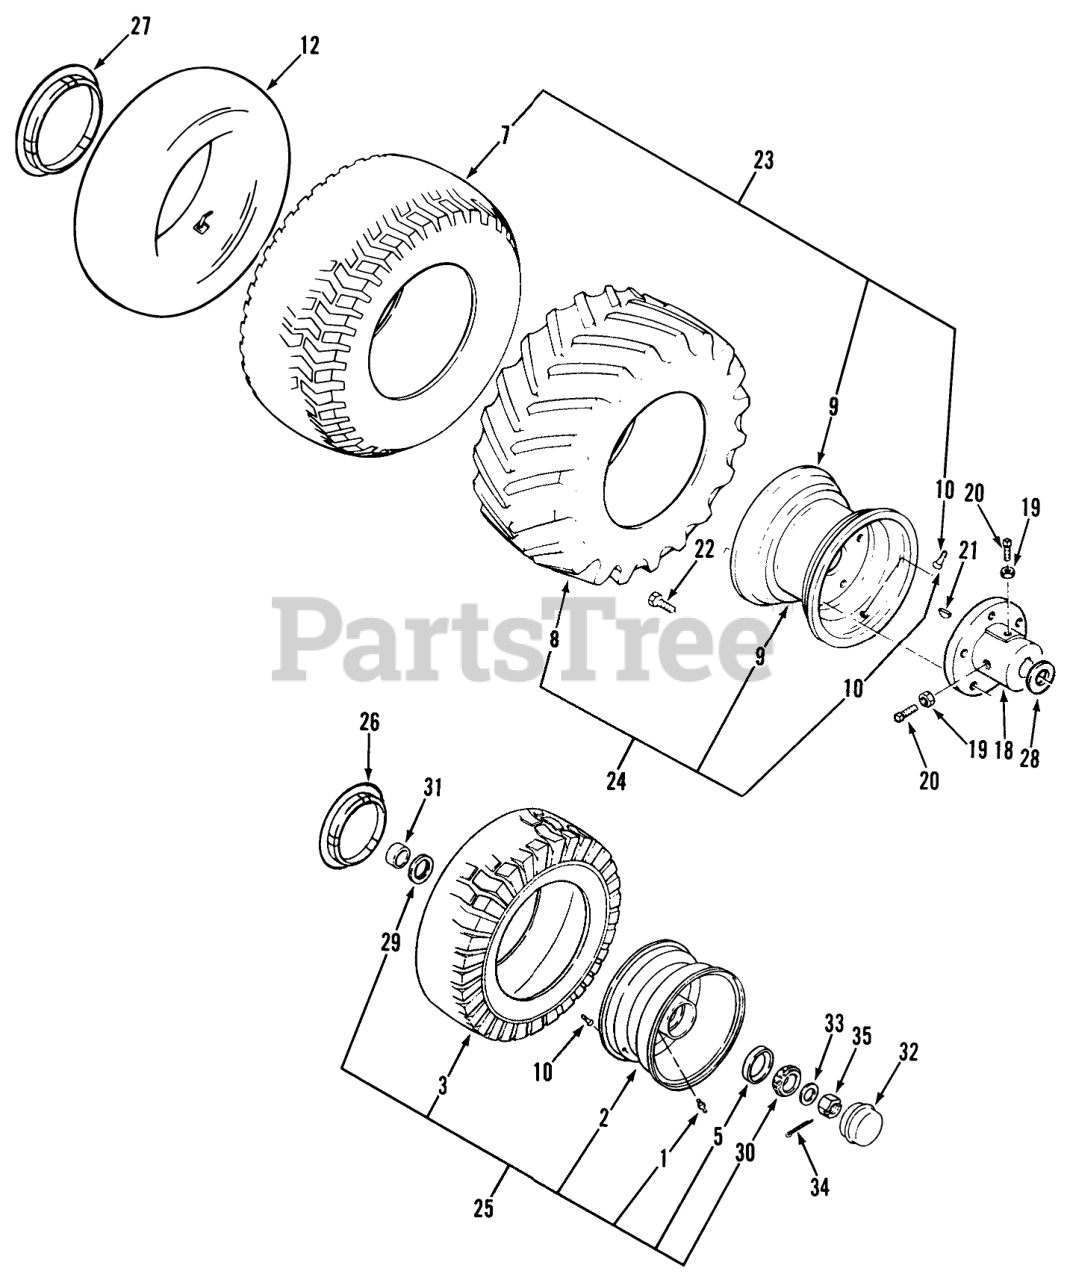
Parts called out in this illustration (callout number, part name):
1	ZERK-GREASE
2	Front Wheel (Includes Item 1 & qty. 2 of Item 5)
3	TIRE-16 X 7.50 TURF
5	Cup
7	TIRE 23 X 10.50-12
8	Tire-Cleat, Rear
9	RIM ASM
10	VALVE
12	Rear Tube
18	Hub Rear
19	Nut
20	Screw-Set
21	KEY-WOODRUFF
22	Lug Nut
23	Rear Wheel & Tire Assy
24	ASSY WHEEL & TIRE
25	Screw, Plate Retaining
26	8"-HUB CAP LOGO
27	12"-HUB CAP LOGO
28	WASHER-THRUST
29	Seal
30	Bearing
31	SPACER
32	DUST CAP
33	Washer
34	Cotter Pin
35	Nut-Slotted 3/4-16
